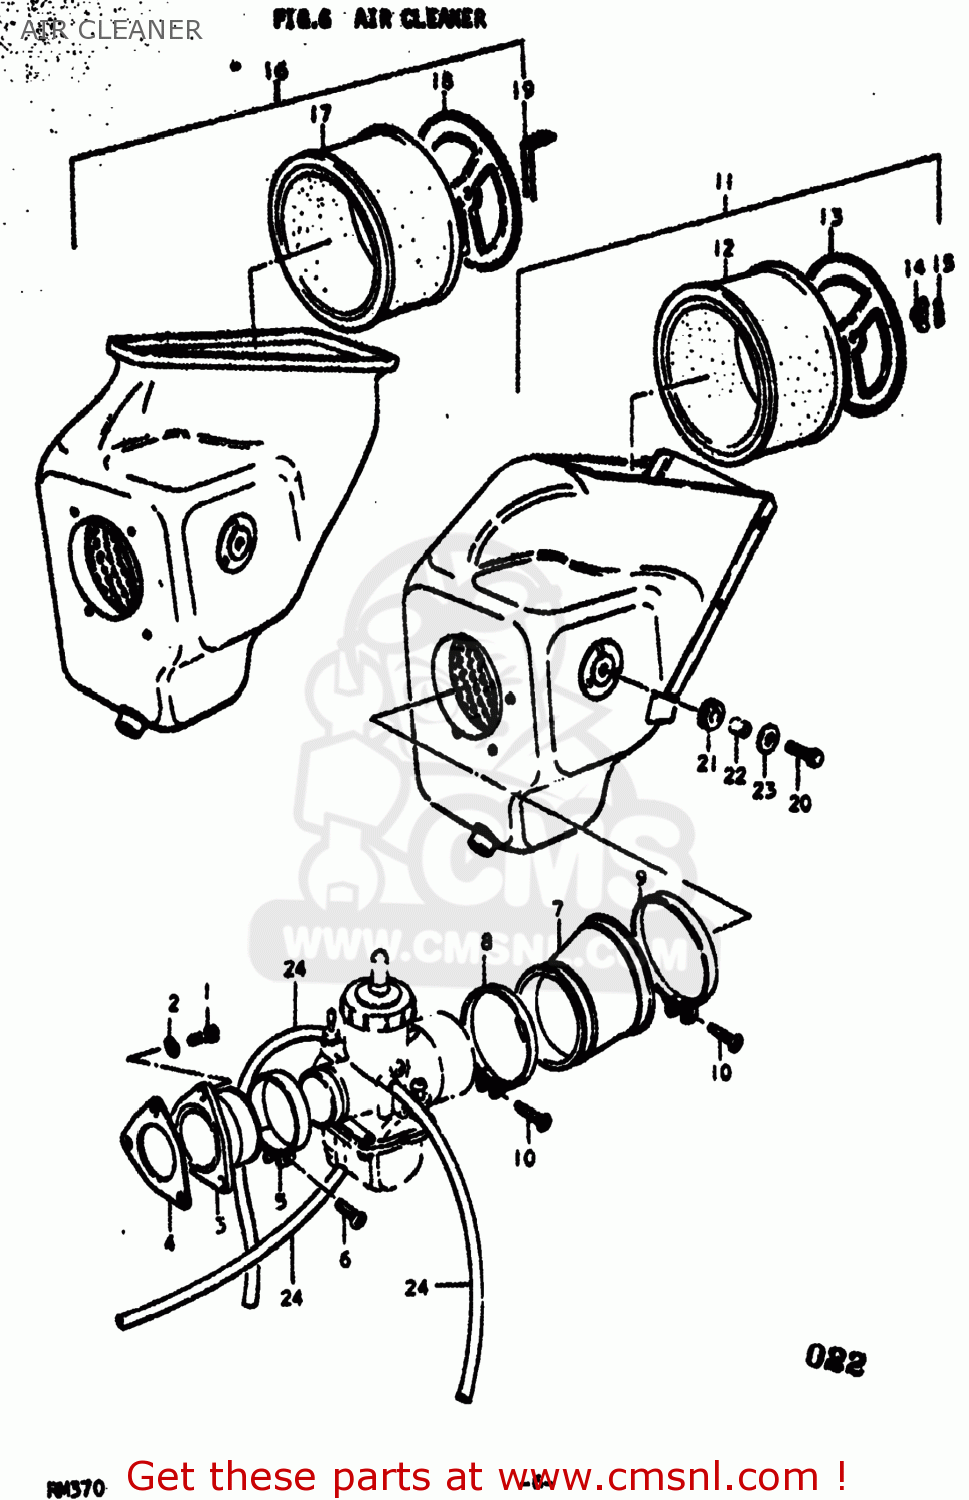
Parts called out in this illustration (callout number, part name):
1	BOLT
2	LOCK WASHER
3	PIPE,INTAKE
4	GASKET,INTAKE PIPE (NAS)
5	CLAMP
6	SCREW
7	TUBE,AIR CLEANER OUTLET
8	CLAMP
9	CLAMP
10	SCREW
11	CLEANER ASSEMBLY,AIR
12	ELEMENT,AIR CLEANER
14	NUT
16	CLEANER ASSEMBLY,AIR
17	FILTER
18	CAP
19	SPRING,AIR CLEANER
20	BOLT
21	CUSHION
22	SPACER (7X9X7)
23	WASHER (6.5X20X1.2)
24	HOSE
